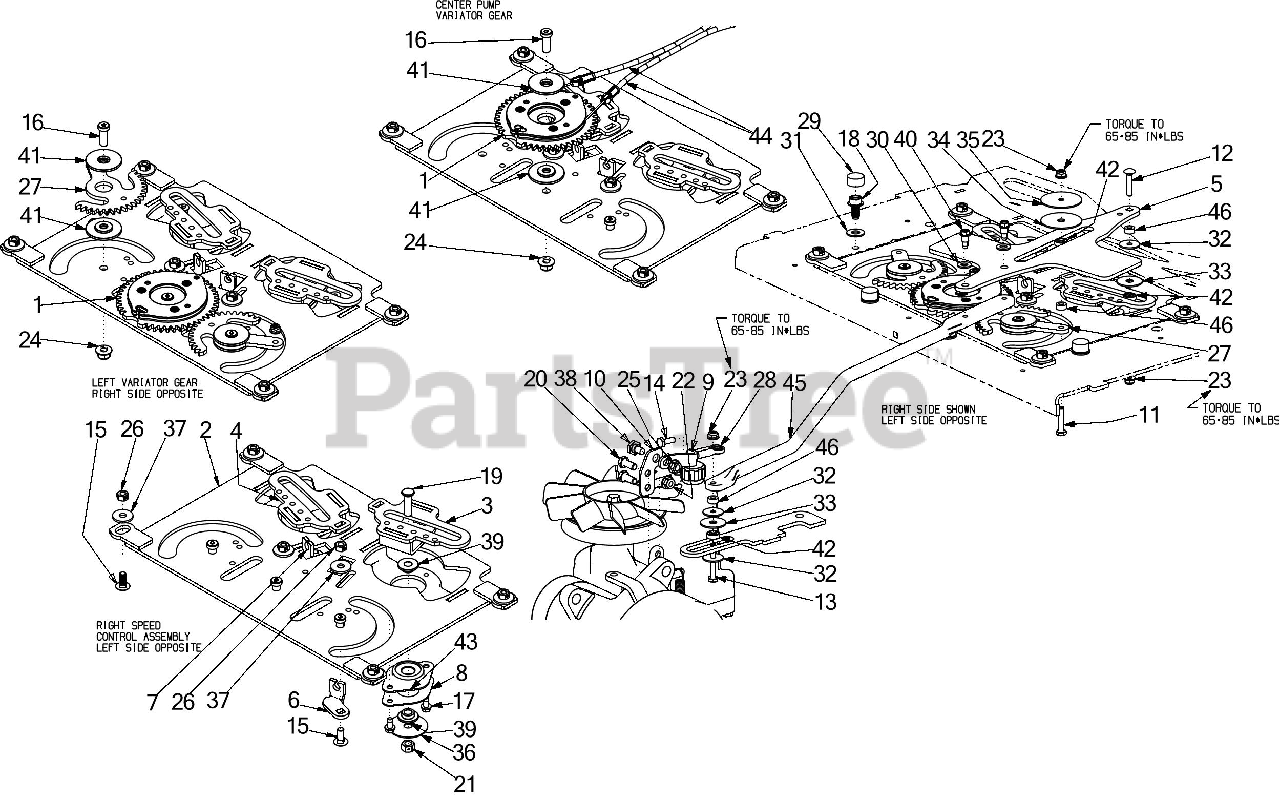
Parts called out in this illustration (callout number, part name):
1	PUMP GEAR
2	CONTROL MOUNT PUMP PLATE
3	CONTROL PUMP CAM ASSEMBLY (RH)
4	CONTROL PUMP CAM ASSEMBLY (LH)
5	ACTUATOR PUMP ARM
6	STEERING CABLE BRACKET
7	CABLE CLAMP BRACKET
8	RETAINING PLATE
9	PUMP BRACKET
10	TRANSMISSION LINK BRACKET
11	HEX SCREW 1/4-20 x 1.25
12	CARRIAGE BOLT 1/4-20 x 1.25 Gr5
13	HEX SCREW 1/4-20 x 1.75
14	HEX SCREW 1/4-28 x .75
15	CARRIAGE BOLT 5/16-18 x .75
16	SCREW 3/8-16 x 1
17	SCREW 1/4-20 X.500
18	SCREW 3/8-16 x 3/4
19	SCREW 3/8-16 x 1.25 GR5
20	SCREW 5/16-18 x .75 GR5
22	FLANGE LOCK NUT 5/16-18
23	FLANGE LOCK NUT
25	FLANGE NUT
26	HEX NUT
27	STEERING GEAR YOKE
28	END ROD (RH)
29	SLIDE CAP
30	FLAT WASHER
31	FLAT WASHER
32	FLAT WASHER
33	WASHER .355X1.25X.06THK
34	FLAT WASHER
35	FLAT WASHER
36	HUB CAP WASHER .406 x 1.92 x .060
37	FLAT WASHER .345X1.0X.100
38	SHOULDER SCREW .437
39	SHOULDER SPACER
40	SHOULDER SCREW
41	SHOULDER SPACER
42	BALL BEARING .25 x .625 SPCL
43	BALL BEARING
44	CONTROL CABLE
45	PUMP CONTROL ROD
